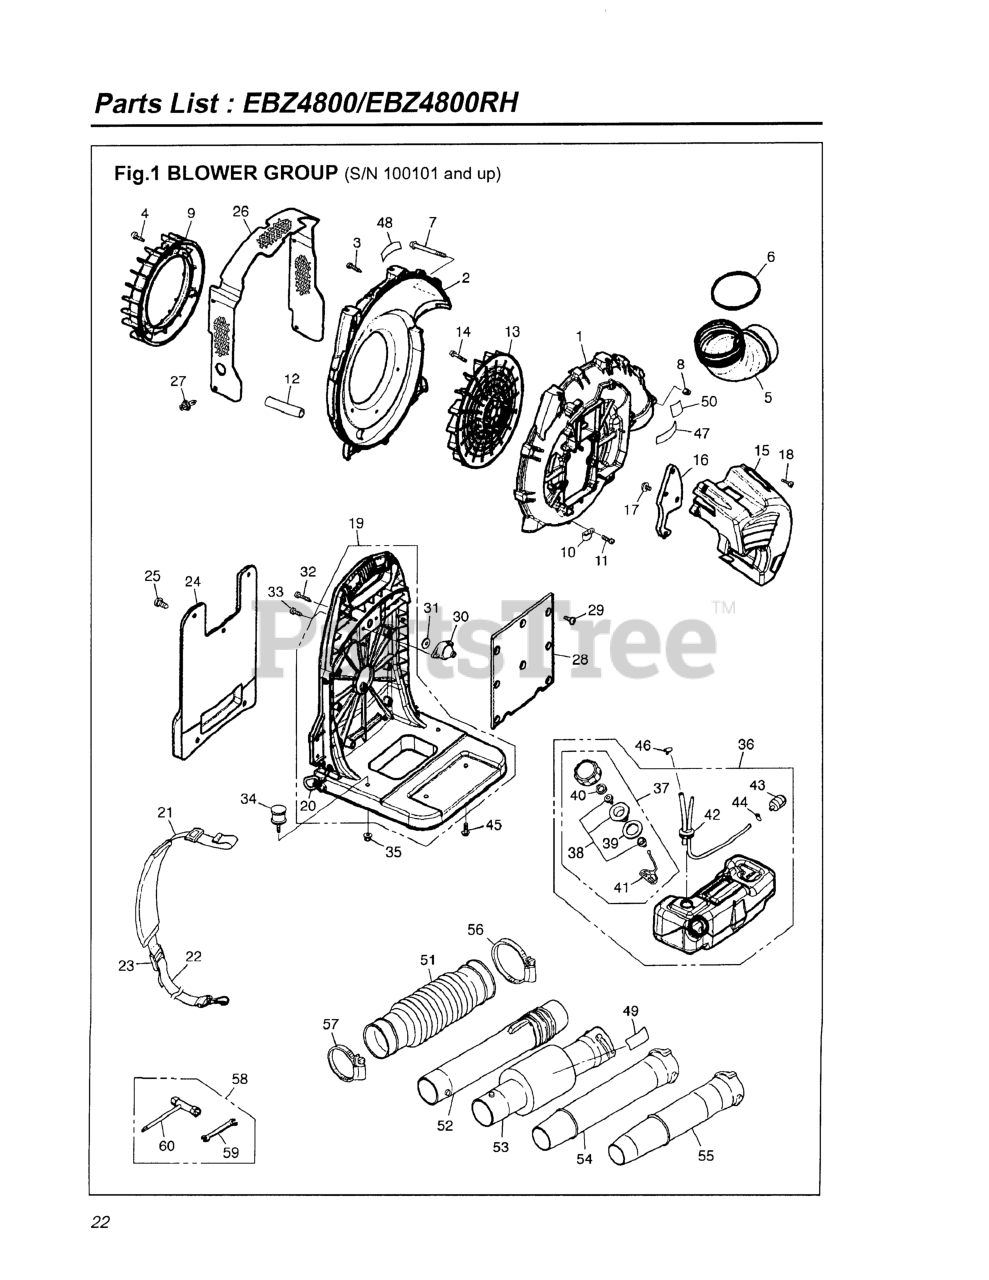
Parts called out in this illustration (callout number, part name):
1	CASE, VOLUTE
3	SCREW
4	SCREW
6	O-RING
7	SCREW TORX
8	NUT (B)
10	CLAMP
12	TUBE (RPLS. 07270-01507)
13	FAN
14	BOLT
15	COVER, ENGINE
16	GLASS
17	SCREW
18	SCREW
19	FRAME COMPLETE
20	RING (REPLACES -21120)
21	USE T4017-32310
24	PAD
25	CLIP (RPLS 3490-21320)
26	NET COMPLETE
27	CLIP
29	SCREW
30	DAMPER, UPPER
31	WASHER
32	SCREW (RPLS T4970-54010)
33	SCREW TORX
34	DAMPER, LOWER
35	NUT, M6
36	TANK ASSEMBLY
37	CAP ASSY (RPLS -85201)
38	HOLDER (REPLACES -85230)
39	PACKING
40	FILTER
41	STOPPER
42	PIPE COMP.(RPLS 2756-85300)
43	FILTER ASSY
44	CLIP (REPLACES 2841-31280)
45	SCREW TORX
46	CLIP
47	LABEL, CAUTION (RPLS -31910)
48	LABEL, NET
49	LABEL, SILENCER
50	LABEL, NOISE
51	HOSE (RPLS 2750-51110)
52	JOINT, SWIVEL (USE 51201)
53	PIPE, SILENCER
54	PIPE, END
55	KIT, NOZZLE (USE 2756-51221)
56	CLAMP (RPLS 3490- )
57	CLAMP (RPLS 3050-13230)
59	SPANNER, 8 X 10 (RPLS 2540- )
